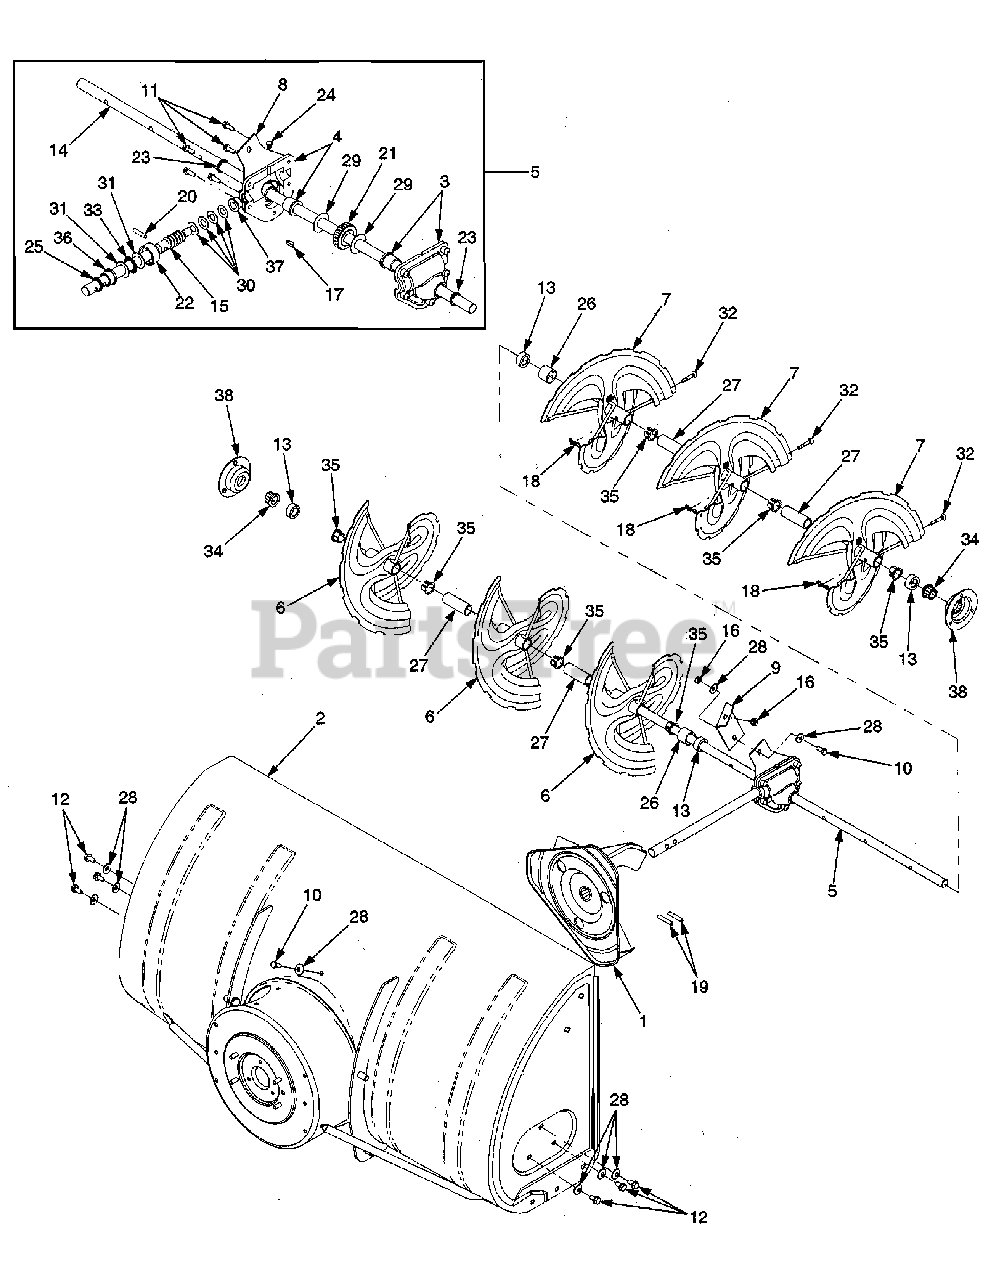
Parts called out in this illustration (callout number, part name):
2	Housing. Auger
3	Housing Assembly. Auger RH
4	Housing Assembly. Auger LH
5	Auger Gear Box Ass'y., Complete .
8	Plate. Housing Brace
9	Bracket. Housing Brace
10	Screw. Hex Cap 5/16-24 x .75 GR5
11	Screw. Hex Wash . Hd Tapp 1/4-20 x .75
12	Screw. Hex Wash . Hd Tapp 5/16-12 x .75
13	Spacer. . 75 x 1.25 x . 5
14	Shaft. Auger
15	Shaft. Worm Gear
16	Nut. Hex. 5116-24 GR5
17	Key. Hi.Pro. 3116 x 518
18	Pin. Bow Tie Cotter
19	Pin. Spiral Spring. 114 x 1-112
20	Pin. Spiral Spring. 114 x 1.25
21	Gear. Worm. 20T
22	Collar. Thrust
23	Seal. Oil
25	Seal. Oil
26	Spacer. . 75 x 1.25 x 1 0 .
27	Sleeve. . 758 x 1 . 0 x 2.7
28	Washer. Bell. 340 x . 872 x . 06
29	Washer. Flat. . 76 x 1.5 x . 030
30	Washer. Flat. . 508 x 1.0 x . 020
31	Washer. Thrust. . 75 x 1.25 x . 062
32	Pin. Shear. . 25 x 1.5
33	Bearing. Thrust.
34	Bearing. Hex Flange
35	Bushing. Flange
36	Bearing. Flange
37	Bearing. Flange
